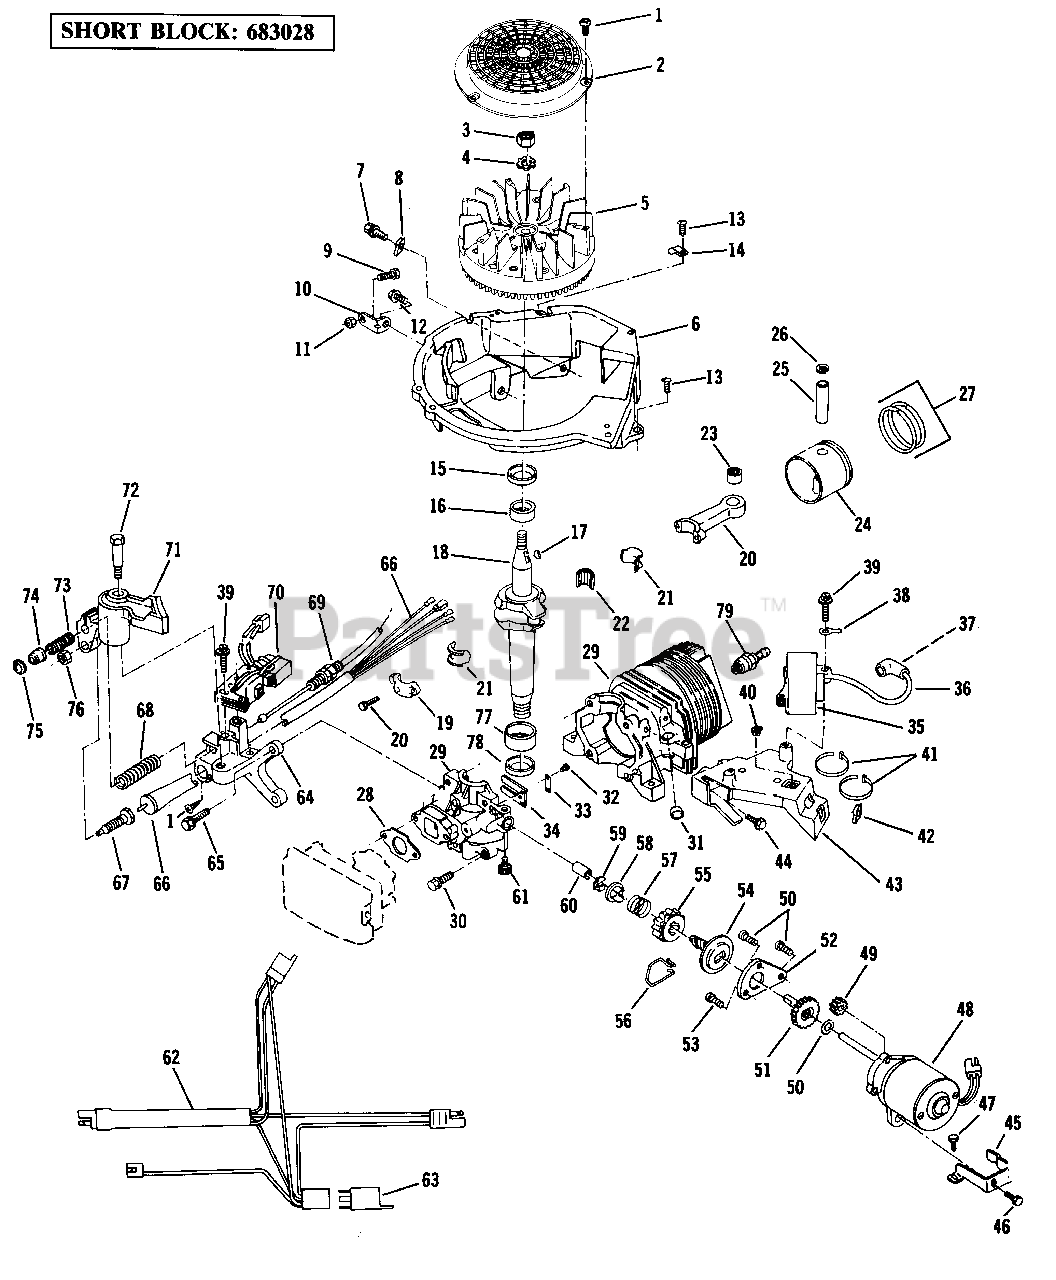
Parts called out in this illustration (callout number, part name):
1	Screw-Flywheel Screen and Switch
2	Screen-Flywheel
3	Nut-Flywheel
4	Lockwasher
5	Flywheel Assembly
6	Base-Shroud
7	Screw
8	Clip-"J"
9	Bolt-Brace-Alt. Brkt.
10	Brace-Alt. Bracket
11	Locknut-Brace-Alt. Brkt.
12	Screw
13	Screw-Shd. Base to C. D. Brkt. and Clamp to Shd. B.
14	Clamp
15	Oil Seal-Upper
16	Bearing-Upper
17	Key-Flywheel
18	Crankshaft
19	Conn. Rod Assembly
20	Screw-Cap
21	Liner-Split
22	Needle Bearing Set
23	Bearing Assembly
24	Piston and Ring Assembly
25	Wrist Pin
26	Retaining Ring
27	Ring Set
28	Gasket-Carb. to Crankcase Cover
29	Cyl. and Crankcase Cov. Ass'y.
30	Screw-Cover to Crankcase
31	Plug
32	Screw-Reed to C'case Cover
33	Plate-Reed Hold Down
34	Reed
35	C.D. Ignition Module and Lead Assembly
36	High Tension Lead
37	Spring Terminal
38	Terminal-Ground Lead
39	Screw-C.D. Mtg. and Alt. Mounting
40	Grommet-C.D. Brkt.
41	Tie Strap
42	Clip-"U"
43	Bracket-Ign. Mounting
44	Screw
45	Bracket-Starter Mtg.
46	Screw
47	Screw
48	Mtr. Hsg. and Pin Assembly
49	Pinion-Motorshaft
50	Washer
51	Gear Driven
52	Plate-Gear Cover
53	Screw
54	Pinion, Spring and Clutch Ass'y.
55	Pinion
56	Spring-Drag
57	Spring-Pinion Return
58	Washer-Pinion Stop
59	Retaining Ring
60	Sleeve
61	Set Screw-Starter Assembly
62	Wire Harness Assembly
63	Relay
64	Bracket-Alt. and Brk. Mtg.
65	Screw-Alt. and Brake Mtg. Brkt.
66	Brake Switch Assembly
67	Plunger
68	Spring-Brake
69	Control Cable Assembly
70	Alternator Assembly
71	Brake Assembly
72	Bolt-Shoulder
73	Spring-Cable Retainer
74	Actuator-Brake Lever
75	Retainer
76	Nut
77	Bearing-Lower
78	Oil Seal-Lower
79	Spark Plug
